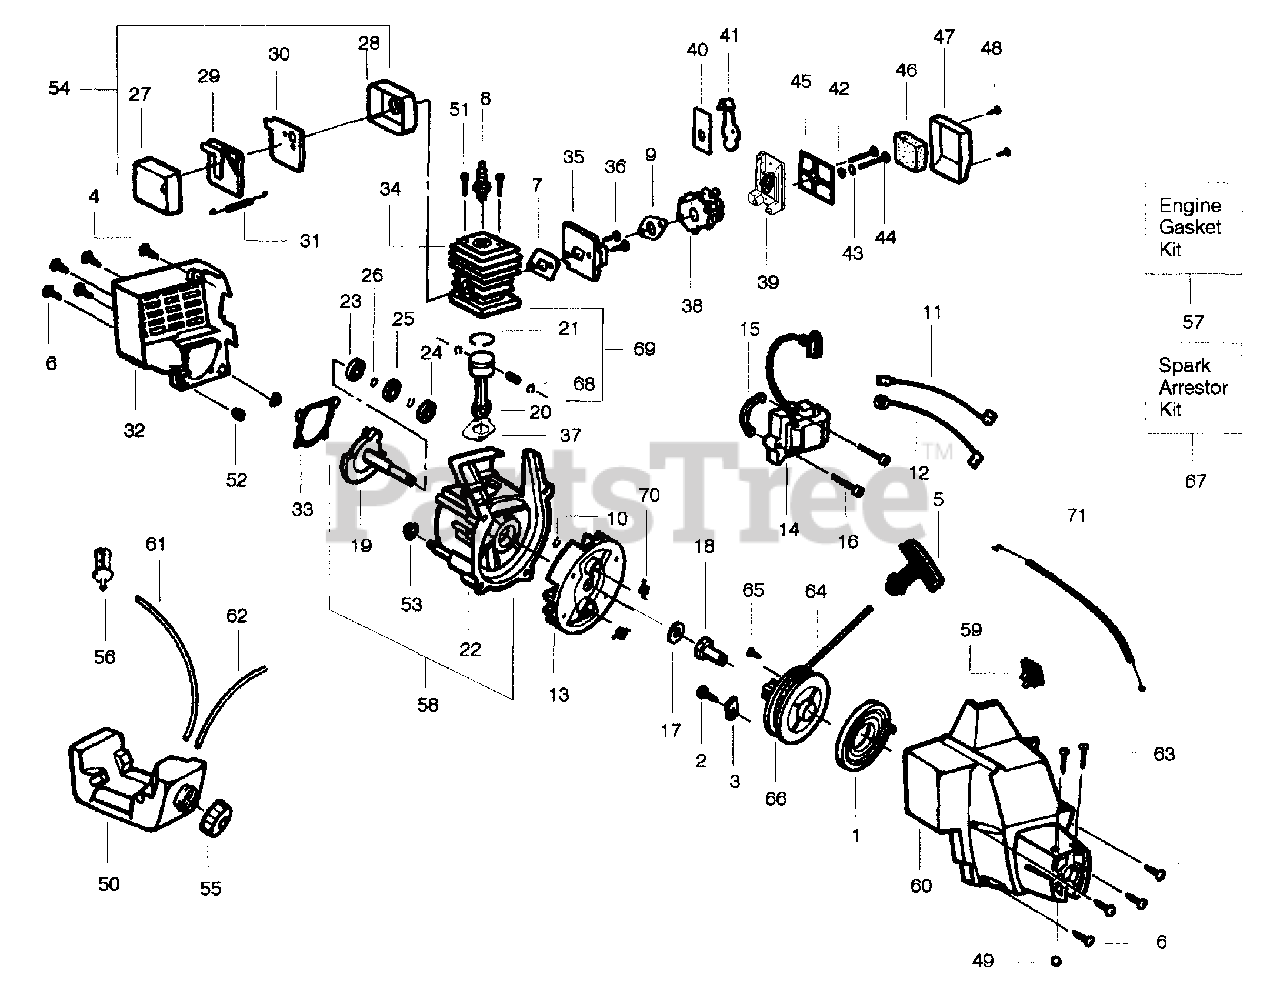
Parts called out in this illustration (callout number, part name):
1	Starter Spring
2	Screw - Pulley
3	Retainer - Pulley
4	Screw - Shrd/Fan Hsg.
5	Starter Handle
6	Screw
7	Gasket - Cylind./Carb.
8	Spark Plug (RCJ 8Y)
9	Gasket - Carb.
10	Retainer Ring - C'case
11	Lead Wire Ass'y.
12	Ground Wire Ass'y.
13	Flywheel Ass'y.
14	Ignition Module
15	Spacer - Ignit. Module
16	Screw - Ignit. Module
17	Washer - Flat
18	Drive Coupling
19	Crankshaft Ass'y.
20	Connecting Rod Ass'y.
21	Piston Ring
22	Crankcase Ass'y.
23	Inner Bearing
24	Outer Bearing
25	C'case Seal
26	Retain. Ring - C'shaft
27	Muffler Body
28	Muffler Cover
29	Muffler Baffle - Exit
30	Muffler Baffle - First
31	Muffler Spring
32	Rear Shroud
33	Gasket - C'case
34	Cylinder
35	Carb. Adapter Kit
36	Screw - Carb Adaptor
37	Gasket - Cylinder
38	Carburetor Ass'y. Kit
40	Choke Plate
41	Choke Shutter
43	Choke Spacer
45	Filter Plate
46	Air Filter Foam
47	Air Filter Cover
50	Fuel Tank Ass'y
51	Screw - Cylinder
52	Isolator - Shroud
53	Isolator - Crankcase
54	Muffler Kit
55	Fuel Cap Ass'y.
56	Fuel Pickup Ass'y.
57	Engine Gasket Kit
58	C'case & C'shaft Assy.
59	On/Off Switch
60	Fan Housing Ass'y
61	Fuel Line - (Small Line)
62	Fuel Line - (Large Line)
64	Rope Kit
65	Screw - Rope Retain.
66	Starter Pulley Kit
67	Spark Arrestor Kit
68	Piston Pin Retainer
69	Piston Kit
70	Starter Dog Spring
71	Throttle Cable Ass'y.
